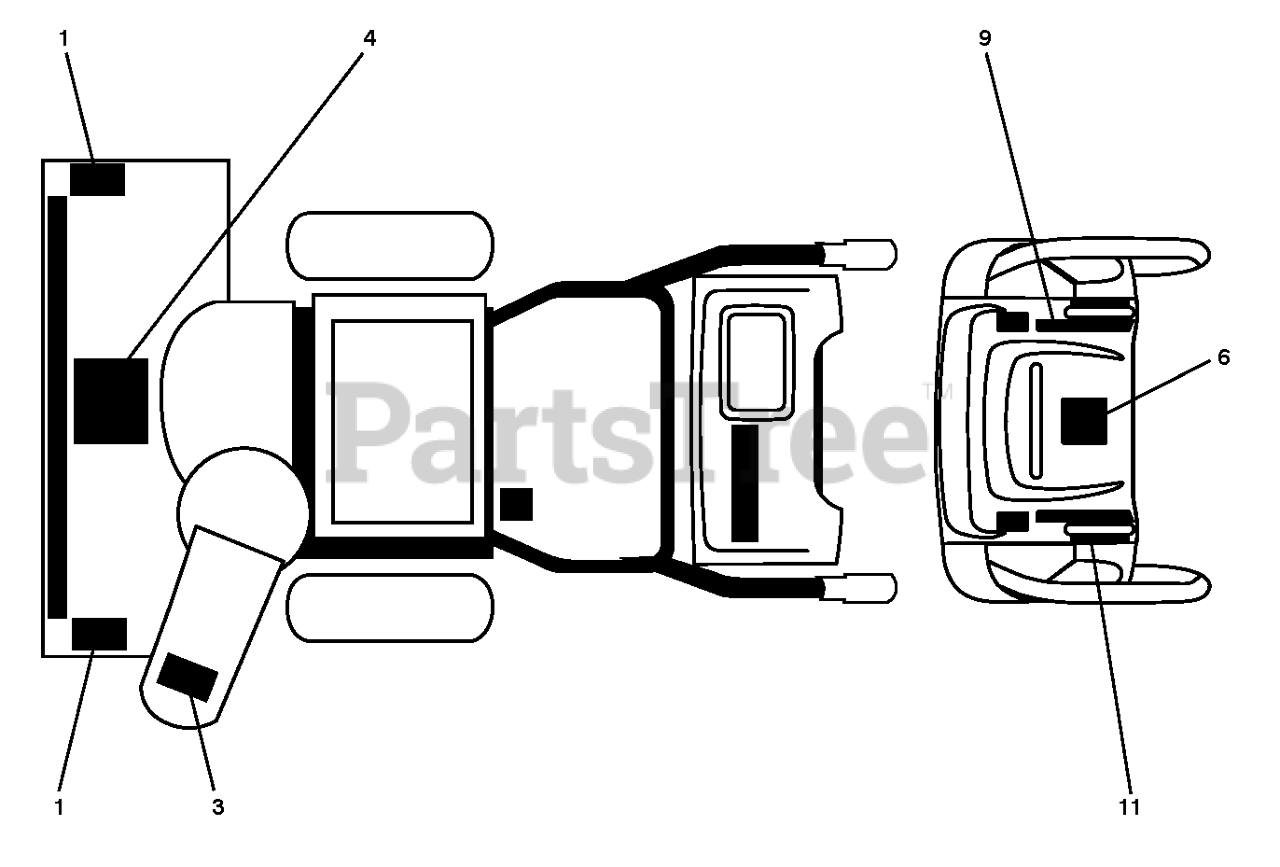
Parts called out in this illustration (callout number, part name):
1	DECAL.SNOWTHR.AUGER
3	DECAL.SNOWTHR.CHUTE.SAFETY
4	DECAL.SNOWTR.READ.OWN.MAN.E/F
6	DECAL.CONSOLE.SNOW.INST.ENG/FR
9	DECAL.CONS.RT.SPD/LEV/PWRST.
11	DECAL.CONS.LT.SPD/LEV/PWRST.
